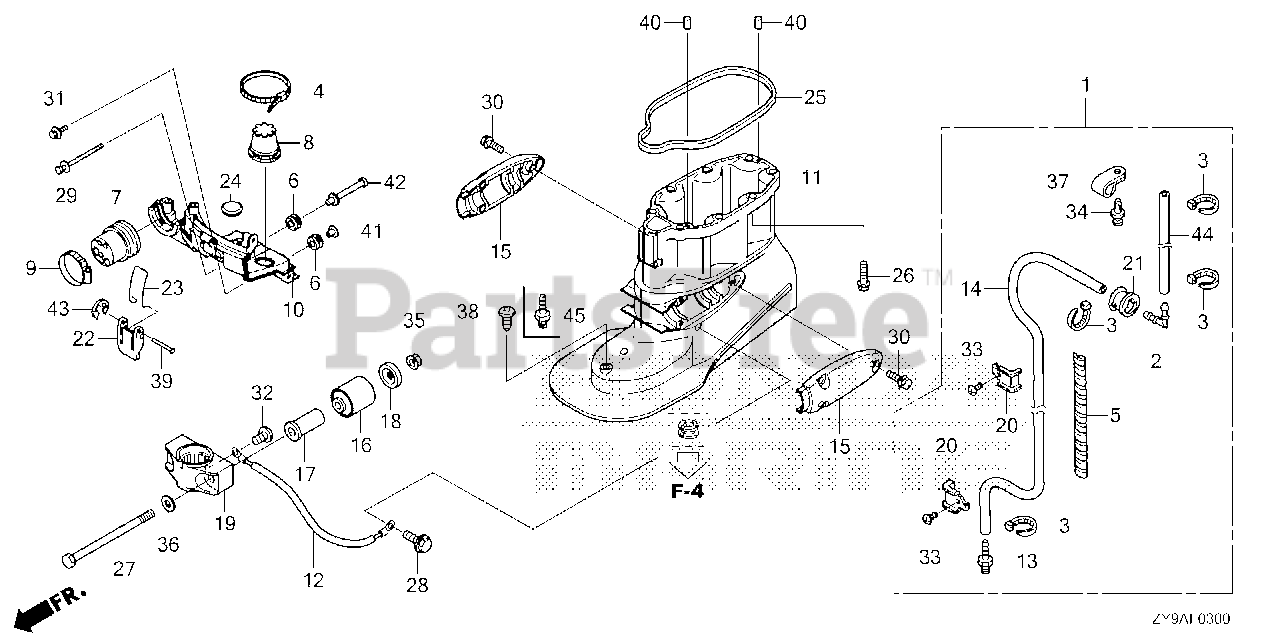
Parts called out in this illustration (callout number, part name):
1	TUBE KIT, SPEED SENSOR
2	JOINT A, BREATHER
3	BAND, WIRE
4	BAND (BLACK 3.5X140)
5	TUBE, SPIRAL
6	GROMMET, CASE (LOWER)
7	GROMMET, REMOTE CONTROL CABLE
8	GROMMET, CASE (LOWER) (C)
9	BAND, CASE GROMMET (LOWER)
10	BRACKET, FR. COVER (LOWER) *NHB14M* (AQUA MARINE SILVER METALLIC)
11	CASE, EXTENSION *NHB14M* (AQUA MARINE SILVER METALLIC)
12	WIRE, LEAD (1.5X137MM)
13	NIPPLE, SENSOR
14	TUBE, SPEED SENSOR
15	HOUSING, MOUNTING (LOWER) *NHB14M* (AQUA MARINE SILVER METALLIC)
16	MOUNT, RUBBER (LOWER)
17	COLLAR, MOUNTING (LOWER)
18	STOPPER, MOUNT (LOWER)
19	HOUSING, CENTER MOUNTING (LOWER) *NHB14M* (AQUA MARINE SILVER METALLIC)
20	PLATE, SPEED SENSOR TUBE
21	BUSH, MOTOR CODE
22	LEVER, FASTENER
23	WIRE, FASTENER
24	CAP, L. SIDE COVER
25	SEAL B, COVER (LOWER)
26	BOLT, FLANGE (10X40)
27	BOLT, HEX. (12X186)
28	BOLT, FLANGE (6X12)
29	BOLT-WASHER (6X95)
30	BOLT-WASHER (8X30)
31	BOLT-WASHER (6X27)
32	SCREW, PAN (6X8)
33	SCREW, PAN (6X8)
34	SCREW, RIVET (5X10)
35	NUT, FLANGE (12MM)
36	WASHER, PLAIN (12MM)
37	CLIP (14MM)
38	CLIP (7MM)
39	PIN (5X44.5)
40	PIN, DOWEL (6X10)
41	COLLAR, MODULE IGNITION CONTROL CASE (CDI)
42	COLLAR, FR. BRACKET
43	E-RING (4MM)
44	BULK HOSE, VACUUM (5X3000) (5X950)
45	NIPPLE, SENSOR
